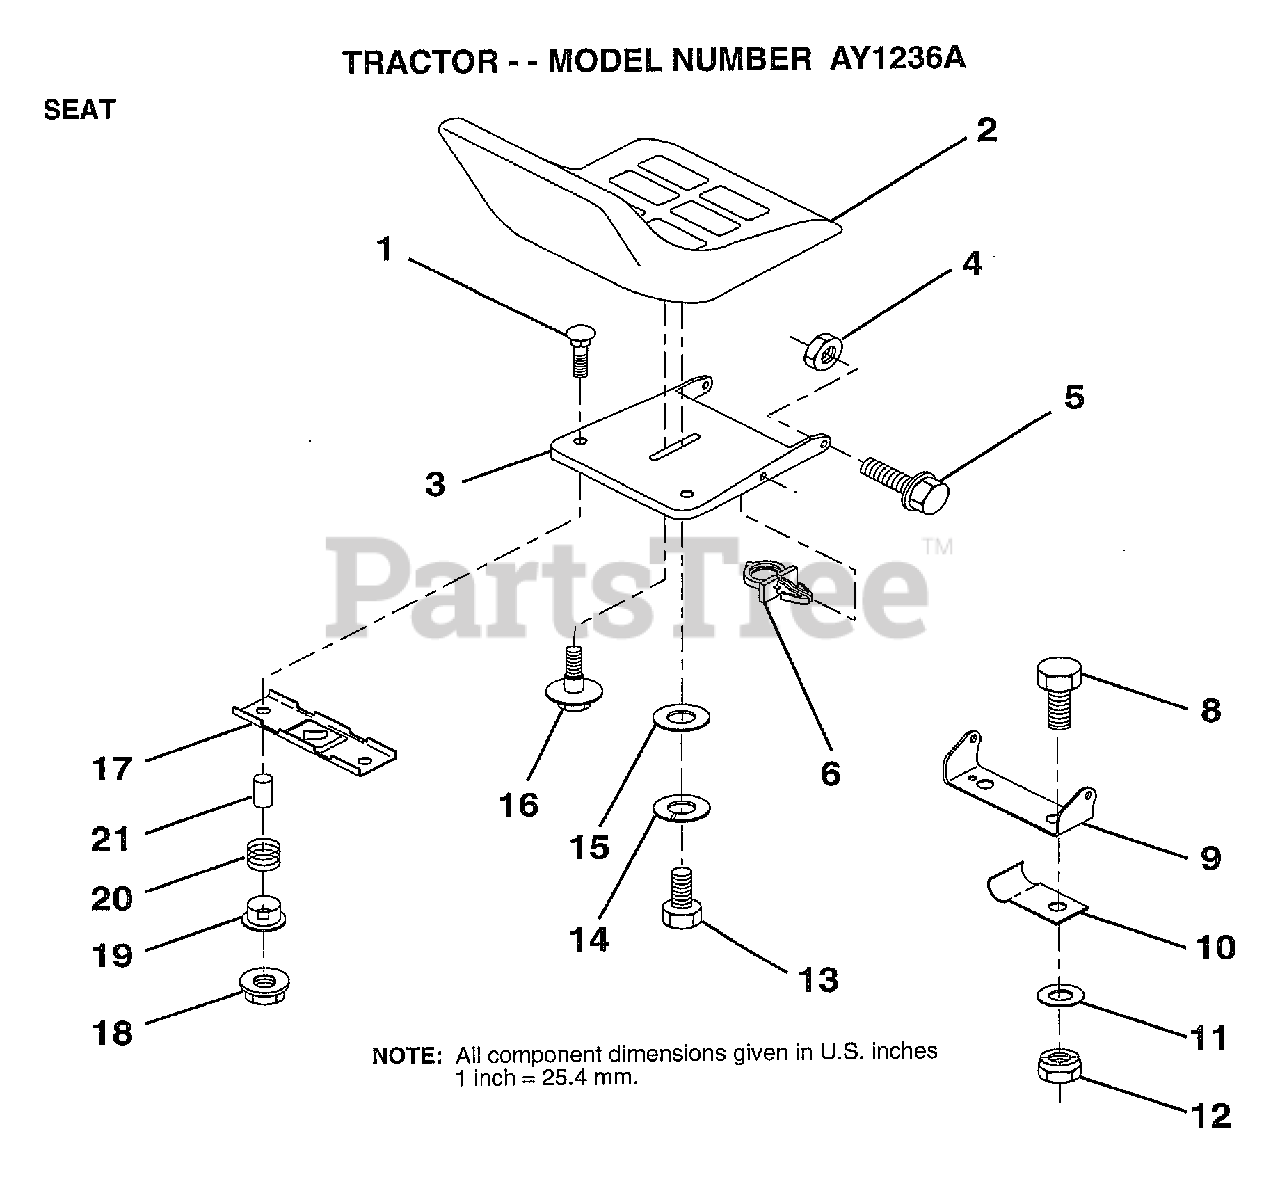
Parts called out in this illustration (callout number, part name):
4	NUT
5	BOLT.SHLD.5/16-18
6	CLIP.PUSH-IN.HING
8	BOLT
9	BRACKET PVT SEAT
10	"CLIP,INSULATOR"
11	WASHER
12	NUT
13	BOLT
14	LOCKWASHER
15	WASHER
16	"BOLT,SHOULDER"
17	BRKT SWITCH
19	BUSHING
20	SPRING
21	SPLIT SPACER
